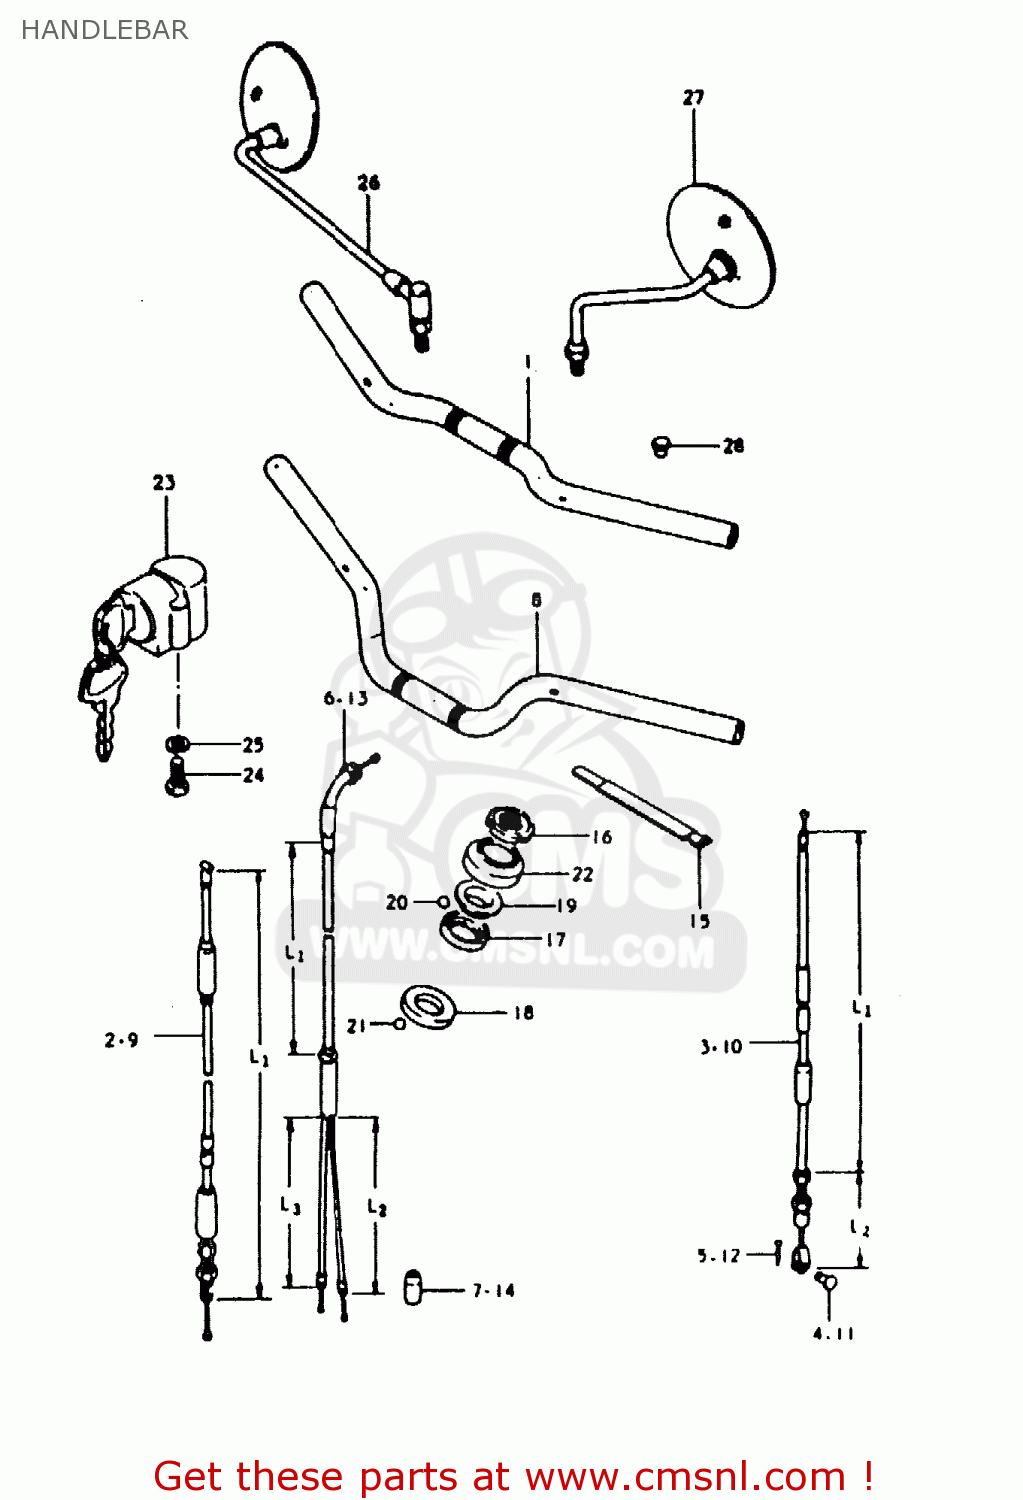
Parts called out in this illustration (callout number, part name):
1	HANDLEBAR FLAT TYPE
2	CABLE, FRONT BRAKE (L1:720) FLAT TYPE
3	CABLE, CLUTCH (L1:800,L2:108) FLAT TYPE
4	PIN(L:13)
5	PIN
6	CABLE, THROTTLE (L1:420,L2:210,L3:310) F
7	SEAL,DUST(7X18X30)
8	HANDLEBAR NEUTRAL TYPE
9	CABLE, FRONT BRAKE (L1:840) NEUTRAL TYPE
10	CABLE, CLUTCH NEUTRAL TYPE
11	PIN(L:13)
12	PIN
13	CABLE ASSEMBLY,THROTTLE
14	SEAL,DUST(7X18X30)
15	CLAMP
16	NUT,STEERING STEM(25X44X10)
17	RACE,STEERING INNER UPR
18	LACE,STEERING INNER LWR
19	RACE,STEERING OUTER UPR
20	BALL
21	BALL
22	DUST SEAL,STEERING UPR
23	LOCK ASSEMBLY,STEERING
24	SCREW
25	LOCK WASHER
26	MIRROR, REAR VIEW
28	CAP
